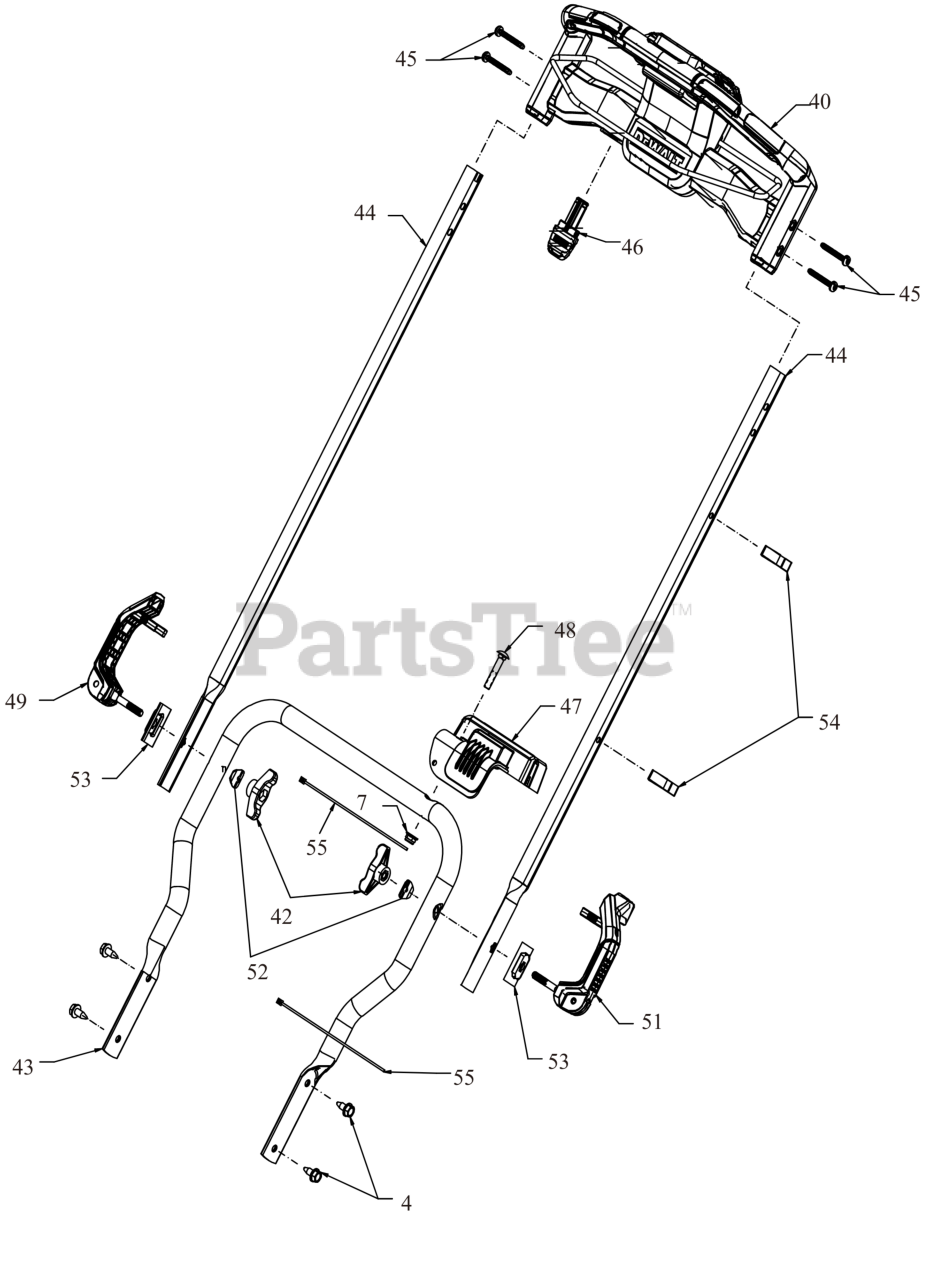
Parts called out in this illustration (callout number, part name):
7	FLANGE LOCK NUT 5/16-18
40	HANDLE PANEL
42	WING KNOB 5/16-18
43	HANDLE (LOWER)
44	HANDLE (UPPER)
45	SCREW M6X45-T30-THD FRM
47	BRACKET
48	CARRIAGE BOLT 5/16-18 x 1.75
49	HANDLE CAMLOCK (RH)
51	HANDLE CAMLOCK (LH)
52	SADDLE WASHER
52	CABLE TIE 2.5X195
53	HANDLE TAB
54	CABLE CLIP
55	CABLE TIE 2.5X195
